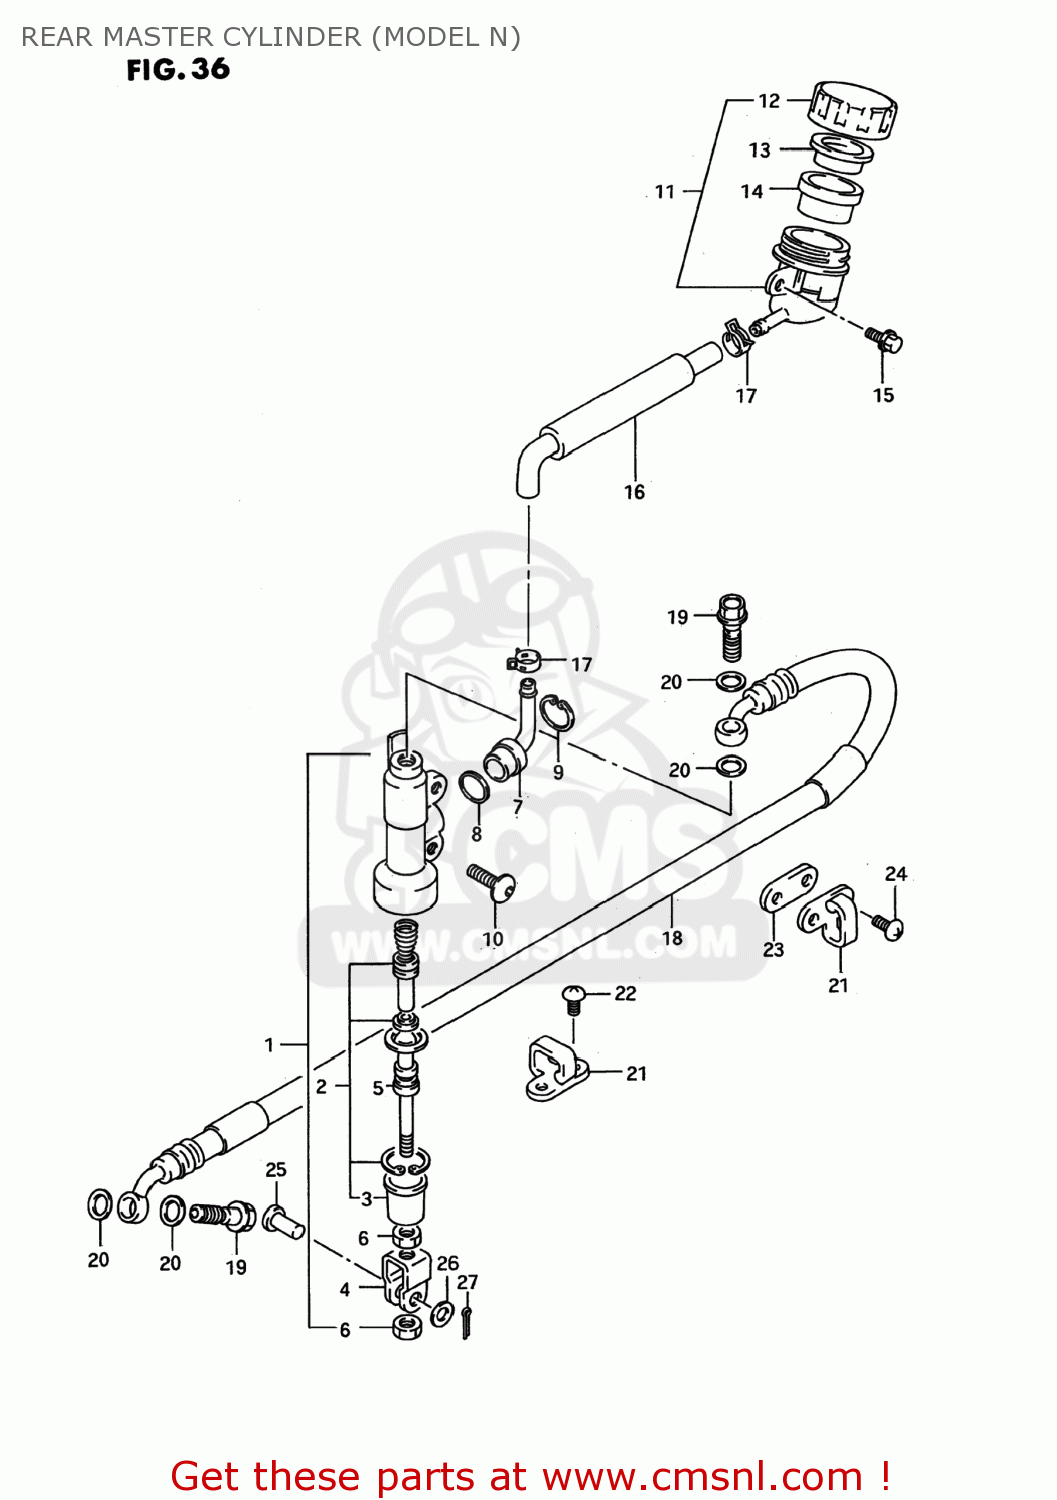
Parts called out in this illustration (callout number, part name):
1	CYLINDER ASSEMBLY,REAR MASTER
2	PISTON/CUP SET
3	BOOT
4	YOKE
5	ROD,PUSH
6	NUT
7	CONNECTOR
8	O RING
9	CIRCLIP
10	SCREW(6X16)
11	TANK ASSY,RR BRAKE RESERVOIR
12	CAP
13	PLATE
14	DIAPHRAGM
15	BOLT
16	HOSE,TANK
17	CLAMP,RESERVOIR HOSE
18	HOSE,REAR BRAKE
19	BOLT UNION
20	WASHER(10X15X1.5)
21	GUIDE,RR BRAKE HOSE
22	SCREW(5X10)
23	SEAT,RR BRAKE HOSE GUIDE
24	SCREW
25	PIN(8X20)
26	WASHER(8.5X13X1.6)
27	PIN
